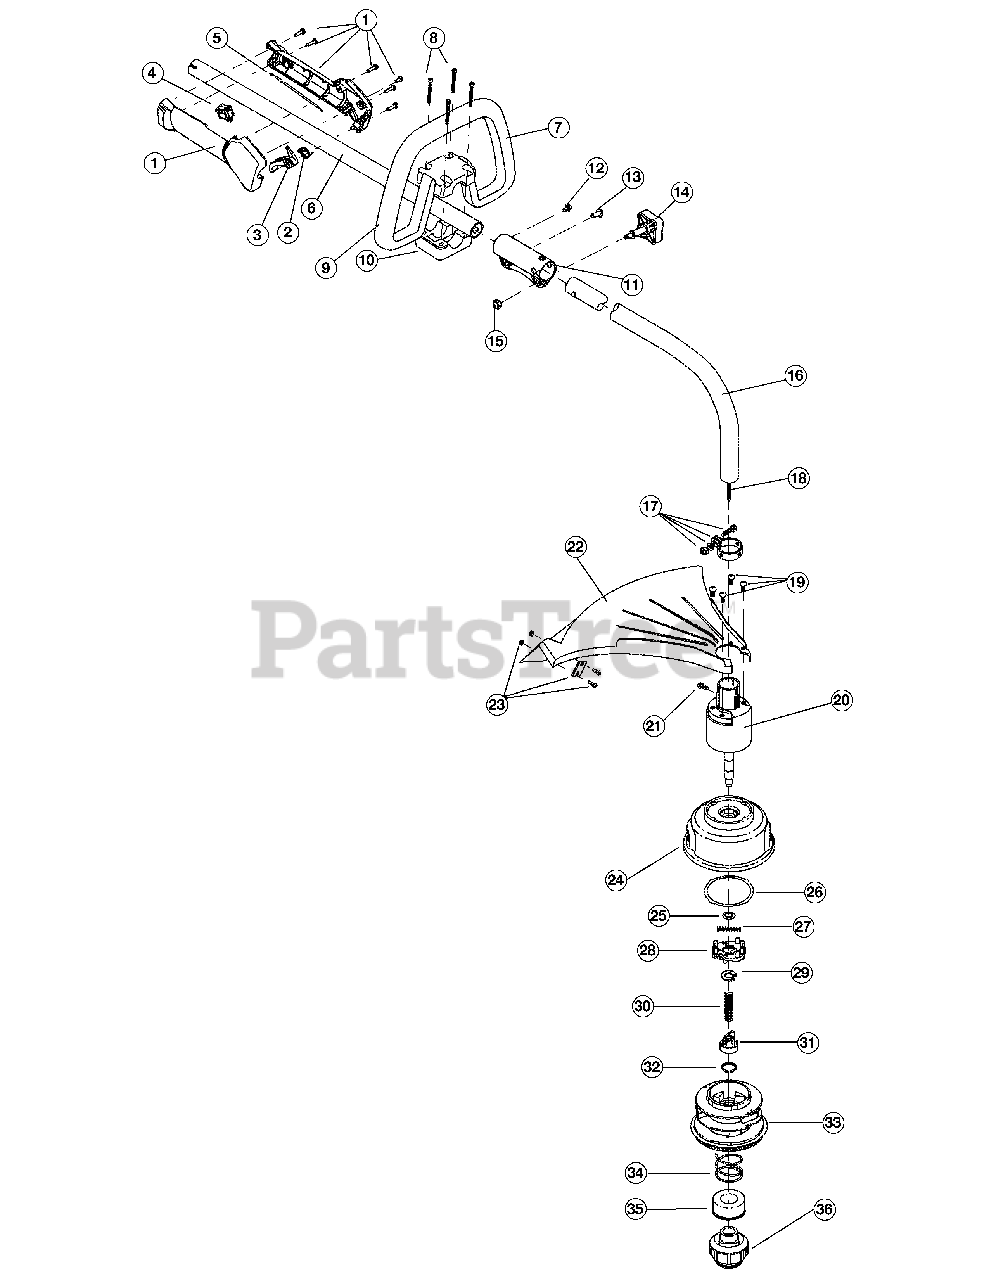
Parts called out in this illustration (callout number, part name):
1	Throttle Housing Assembly (includes 2-4)
2	Throttle Trigger Spring
3	Throttle Trigger
5	Throttle Cable Assembly
6	Upper Drive Shaft Housing Assembly
7	Deluxe D-Handle Assembly (includes 8-10)
9	Deluxe D-Handle
10	Bottom Clamp
11	Split boom Coupler (includes 12-15)
14	Adjustment Knob (includes 15)
15	Knob Retaining Nut
16	Lower Drive Shaft Housing Assembly
17	Lower Clamp Assembly (includes 21)
18	Lower Flexible Drive Shaft
19	Shield Mounting Screw
20	Bushing Housing Assembly
21	Anti-Rotation Screw
22	Shield Assembly (includes 23)
23	Blade Assembly
24	Outer Spool Assembly (includes 25)
26	Thrust Washer
27	Small Spring
33	Inner Reel
34	Large Spring
36	Bump Head Knob Assembly (includes 34 & 35)
